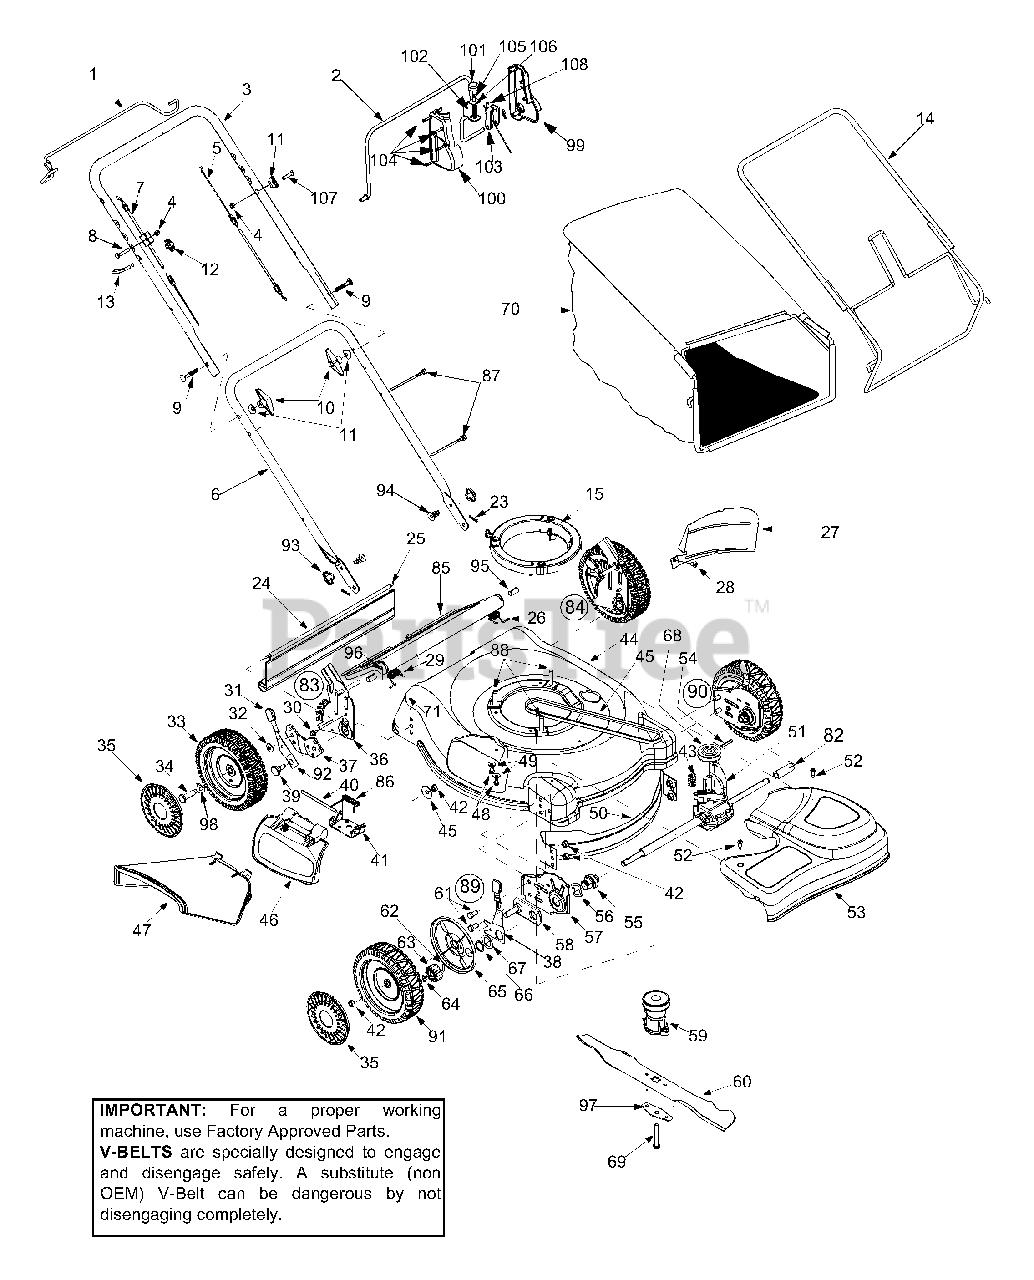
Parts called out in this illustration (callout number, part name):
5	Control Cable
7	Drive Cable
8	Hex Screw 1/4-20 x 1.5"
9	Carriage Bolt
10	Handle Knob
11	Saddle Washer
12	Wing Nut
13	Rope Guide
15	Engine Spacer Assembly
23	Hairpin Clip
24	Rear Trail Shield
25	Wire: Trail Shield
26	Torsion Spring LH
28	Scr. AB 1/4-14 x 0.625"
29	Torsion Spring RH
30	Hex Scr. w/ Wash. 1/4-14 x 0.62"
31	Knob
32	Bell Washer.375 x.870
33	Wheel: Rear w/Ball Brg.
34	Shoulder Screw
35	Hubcap
38	Front Lever RH
39	Shoulder Screw
40	Hinge Pin
41	Chute Deflector Bracket
42	Hex Nut
43	Belt Tension Spring
46	Mulch Plug Assembly
47	Discharge Deflector SD
48	TT Screw 1/4-20 x 0.5"
49	Bell Washer 0.265" x 0.75"
52	Shoulder Screw
53	Front Drive Cover: Yellow
54	Roll Pin
55	Bearing Assembly
56	Wave Washer
58	Pivot Plate Assembly
59	21" One Piece Blade Adapter
60	Mulching Blade w/ Star: 21"
61	Hex Screw
62	Dowel Pin
63	Gear 14T RH
64	Snap Ring
65	Wheel Dust Cap
66	Snap Ring
67	Washer DD 1.5" O.D.
68	Input Pulley
69	Hex Bolt
70	Grass Bag
82	Slev. Spacer LH
83	Height Adj. Assembly RH Compl.
84	Height Adj. Assembly LH Compl.
85	RD Chute Door
86	Torsion Spring
87	Cable Tie
88	TT Screw
89	Height Adj. Assembly RH Compl.
90	Height Adj. Assembly LH Compl.
91	Wheel: Front
92	Spring Lever
93	Wing Nut
94	Hex Carriage Screw 1/4-20
95	Spacer.390OD x.810ID x.950"
96	Rear Door Pivot Rod
97	Blade Bell Support
98	Wave Washer
99	Control Lever LH
100	Control Cover RH
101	Button
102	Compression Spring
103	Lever
104	Hi-Low Screw
106	Retention Ring
107	Hex Hd. Cap Screw
108	Torsion Spring
